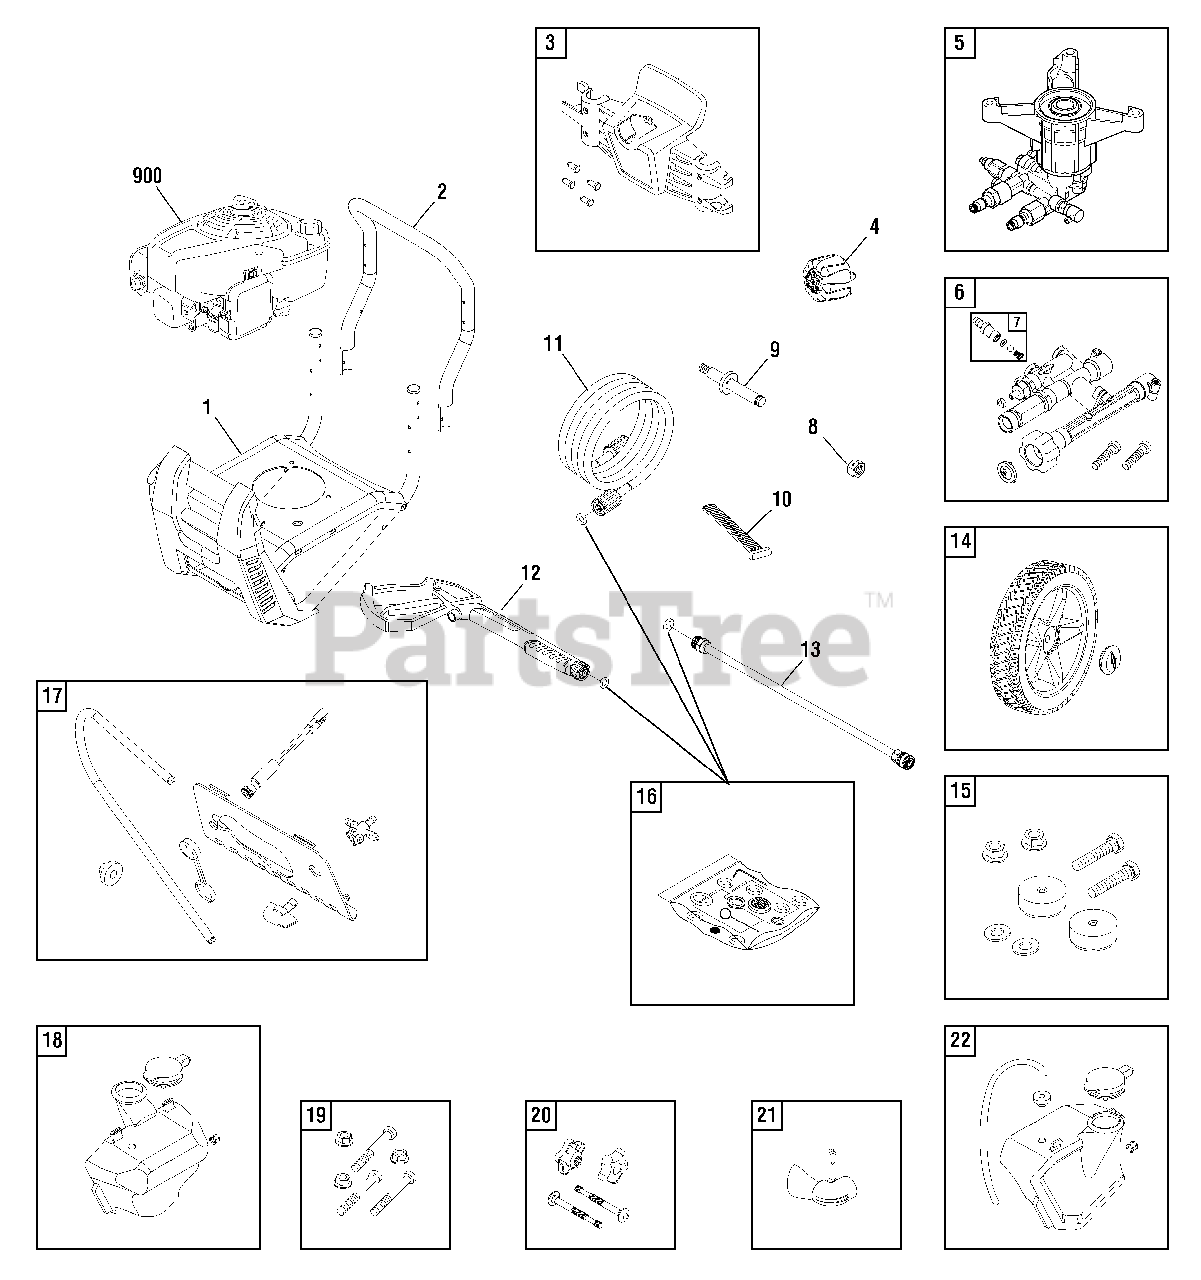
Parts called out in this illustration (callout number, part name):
5	PUMP
6	POWERFLOW
12	GUN
15	MOUNT-VIBRATION
17	PANEL-FRONT ASSY
18	TANK-CHEMICAL, LH
19	KIT-HARDWARE PUMP MOUNTING
20	KIT-HARDWARE HANDLE
21	DEFLECTOR-EXHAUST
22	TANK-CHEMICAL, RH
900	** ENGINE
